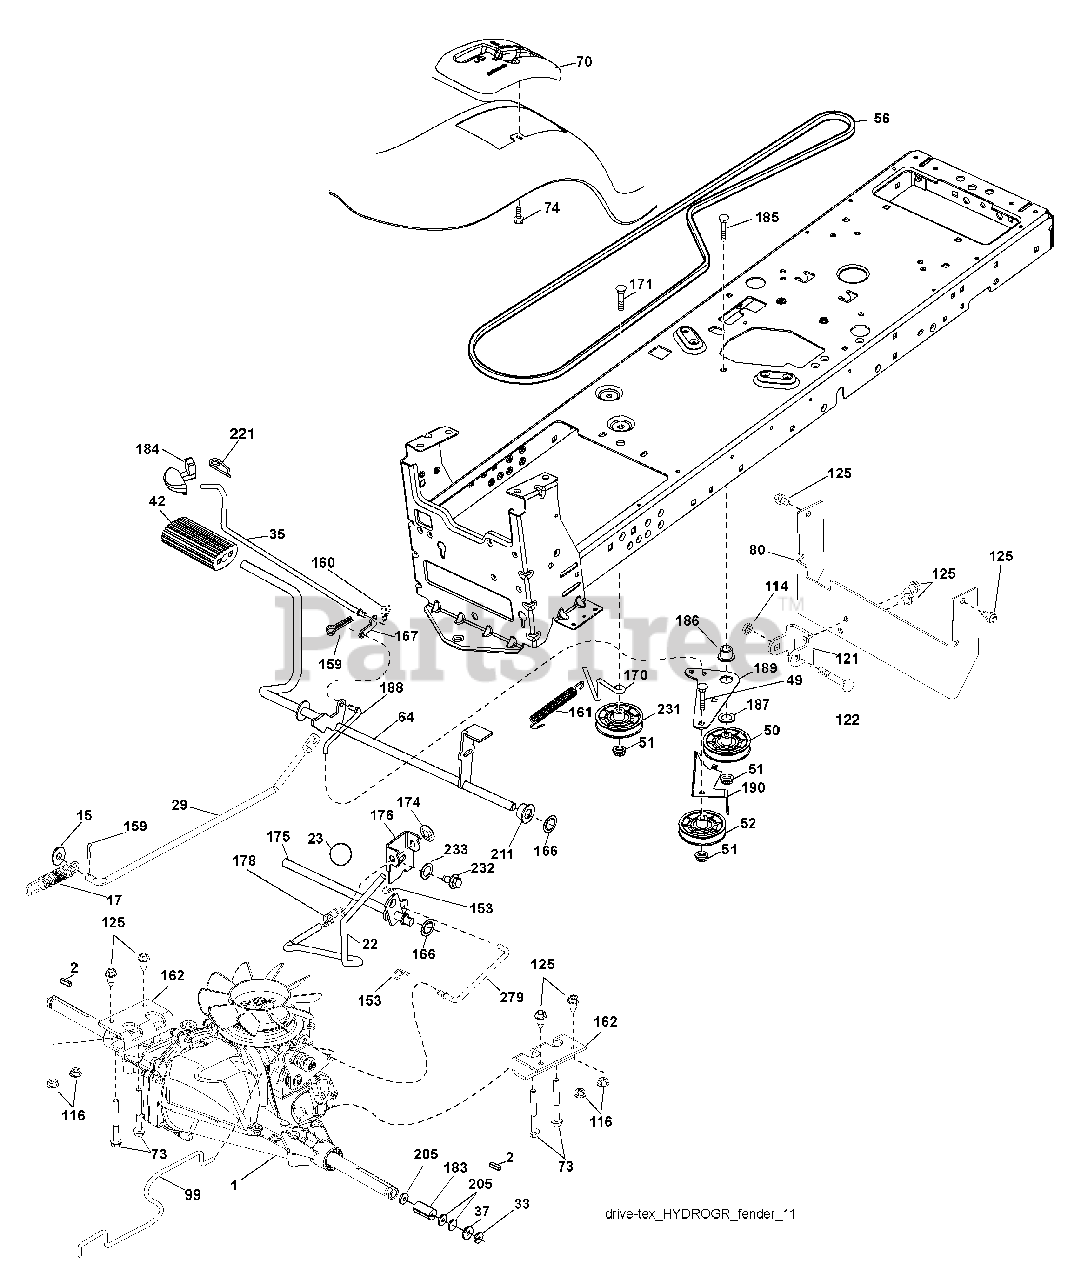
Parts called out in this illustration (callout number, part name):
2	Key Square
15	Washer 13/32 x 13/16 x 16 Ga.
17	Spring, Brake
29	Rod, Brake
35	Rod, Brake, Park
37	Washer 25/32 x 1-1/4 x 16 Ga.
42	Cover, Foot Pedal
50	Pulley Idler Flat
51	Lock Nut 3/8-16
52	Idler V-Groove 910" Offset
56	V-Belt, Drive
64	Shaft Asm. Pedal Brake Control
70	Console
73	Bolt Hex 5/16-18 Gr. 5
74	Screw 1/4 x 1/2
80	Strap Torque
99	Rod Spring Bypass
114	Nut Lock 5/16-18 unc
116	Nut Lock Hex Flange 5/16-18
121	Bracket Strap Torque
122	Bolt 5/16-18 x 2.50
125	Screw 5/16-18 x 3/4
153	Retainer Spring 1"
159	Pin Cotter 1/8 x 3/4
160	Retainer Clip
161	Spring, Return, Clutch
162	Adapter, Transaxle T2
166	Nut Push .625
167	Latch Brake Parking
170	Keeper Belt Centerspan
175	Shaft Asm Shift
176	Arm Clevis Rod Shift
178	Spring Shift
183	Spacer Axle
184	Handle Parking Brake
186	Spacer Retainer
187	Washer
188	Link Clutch Ground Drive
189	Bellcrank Ground Drive
190	Keeper Bellcrank Ground Drive
205	Washer 25/32 x 1-5/8 x 16 Ga.
221	Retainer Spring Clip Handle
231	Idler V-Groove 1.688" Offset
232	Bolt 7/16-14 x 1 Gr 5
233	Washer Serrated
279	Link Shift
